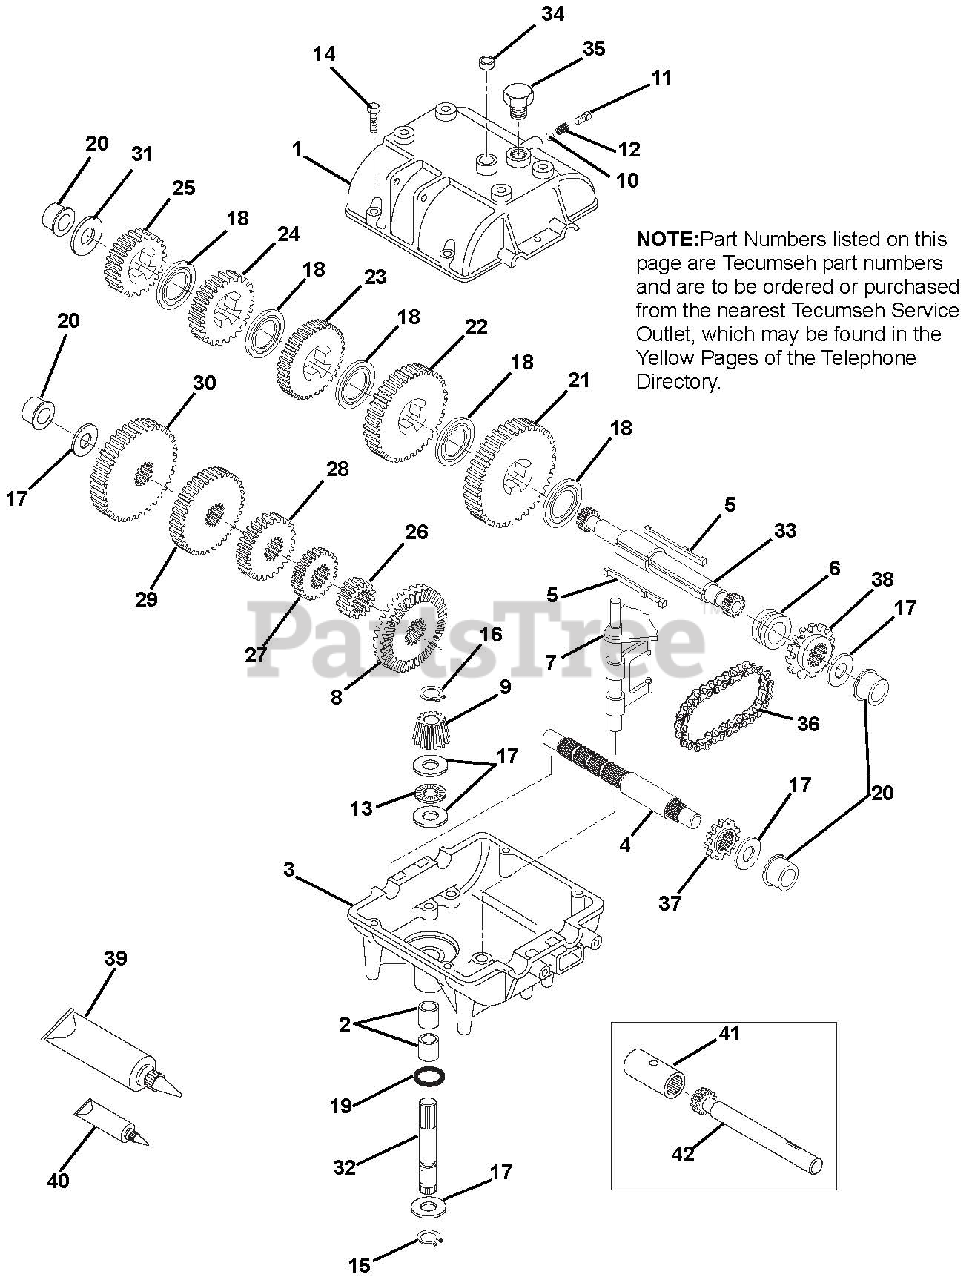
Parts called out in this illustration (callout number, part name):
1	Transmission Cover
2	Needle Bearing .625 ID x .50
2	Needle Bearing .625 ID x .75
3	Transmission Case
4	Countershaft
5	Shift Key
6	Shift Collar
7	Shift Rod & Fork Assembly
8	Bevel Gear
9	Bevel Pinion
10	Steel Ball .31 Diameter
11	Set Screw .38-16 x .38
13	Thrust Bearing
14	Screw .25-20 x 1.25
15	Ring, Retaining
16	Ring, Retaining
19	"O"-Ring
20	Bushing-Flanged
21	Spur Gear
22	Spur Gear
23	Spur Gear
24	Spur Gear
25	Spur Gear
26	Spur Gear
27	Spur Gear
28	Spur Gear
29	Spur Gear
30	Spur Gear
32	Input Shaft 3.69 long
33	Shifter and Brake Shaft
34	Square Cut Ring
35	Threaded Plug
36	Roller Chain
37	Sprocket
38	Sprocket
39	Grease
40	Gasket Eliminator
41	Optional Coupling
42	Optional Connector
